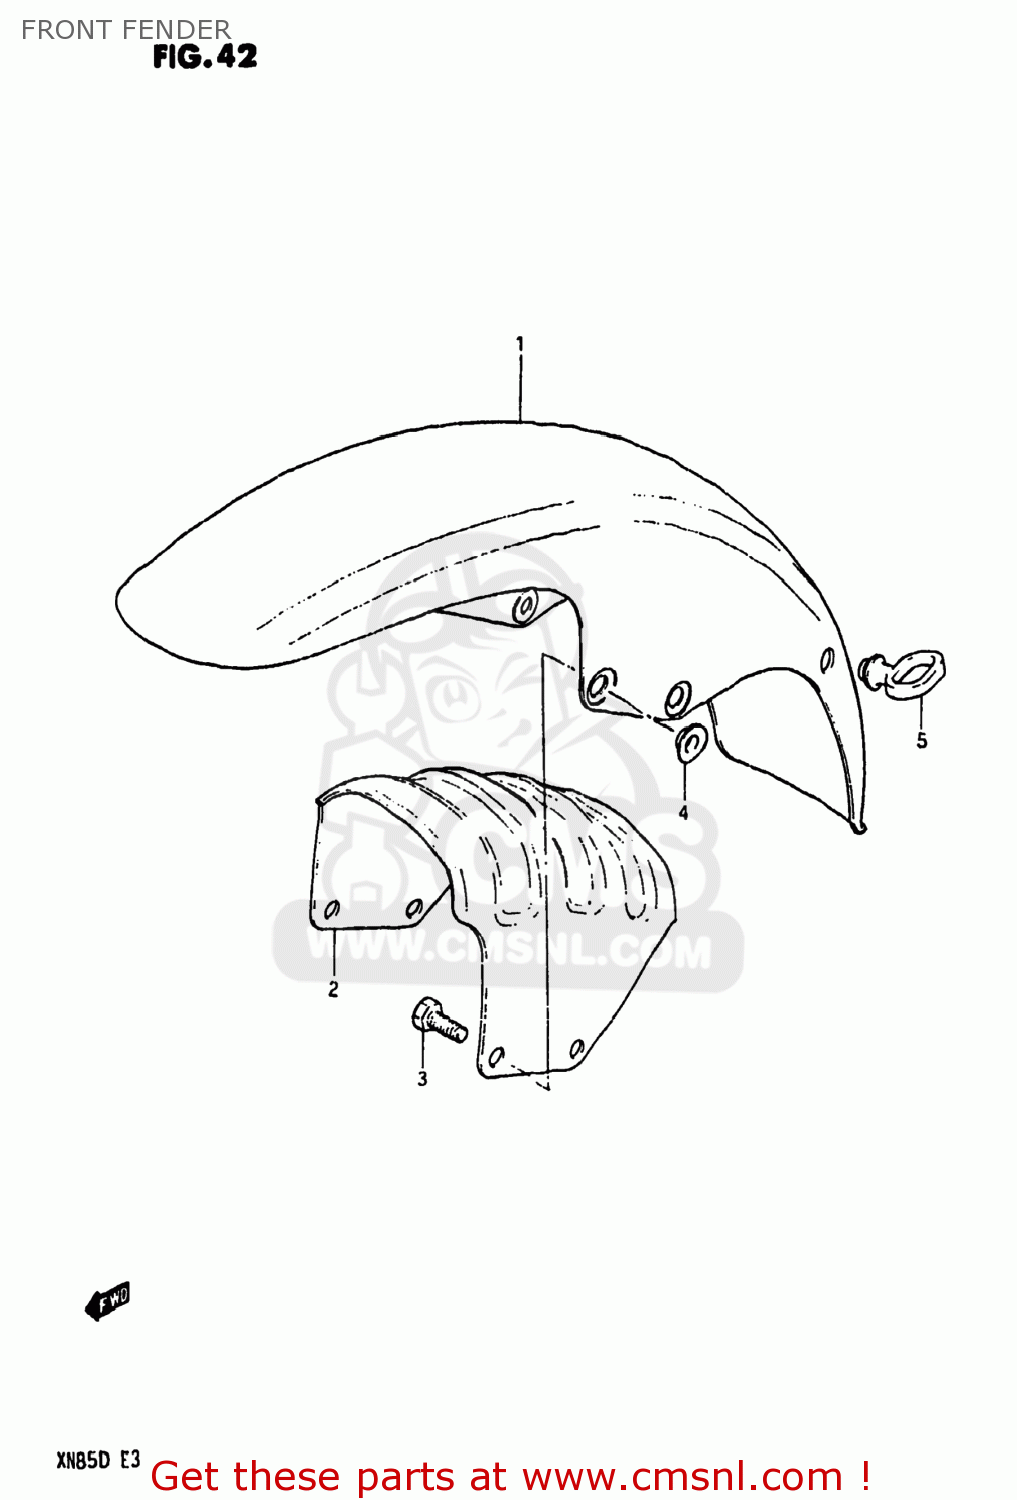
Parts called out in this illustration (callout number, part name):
1	FENDER,FRONT
2	BRACE,FRONT FENDER
3	BOLT 8X16
4	WASHER
5	GUIDE,CABLE
